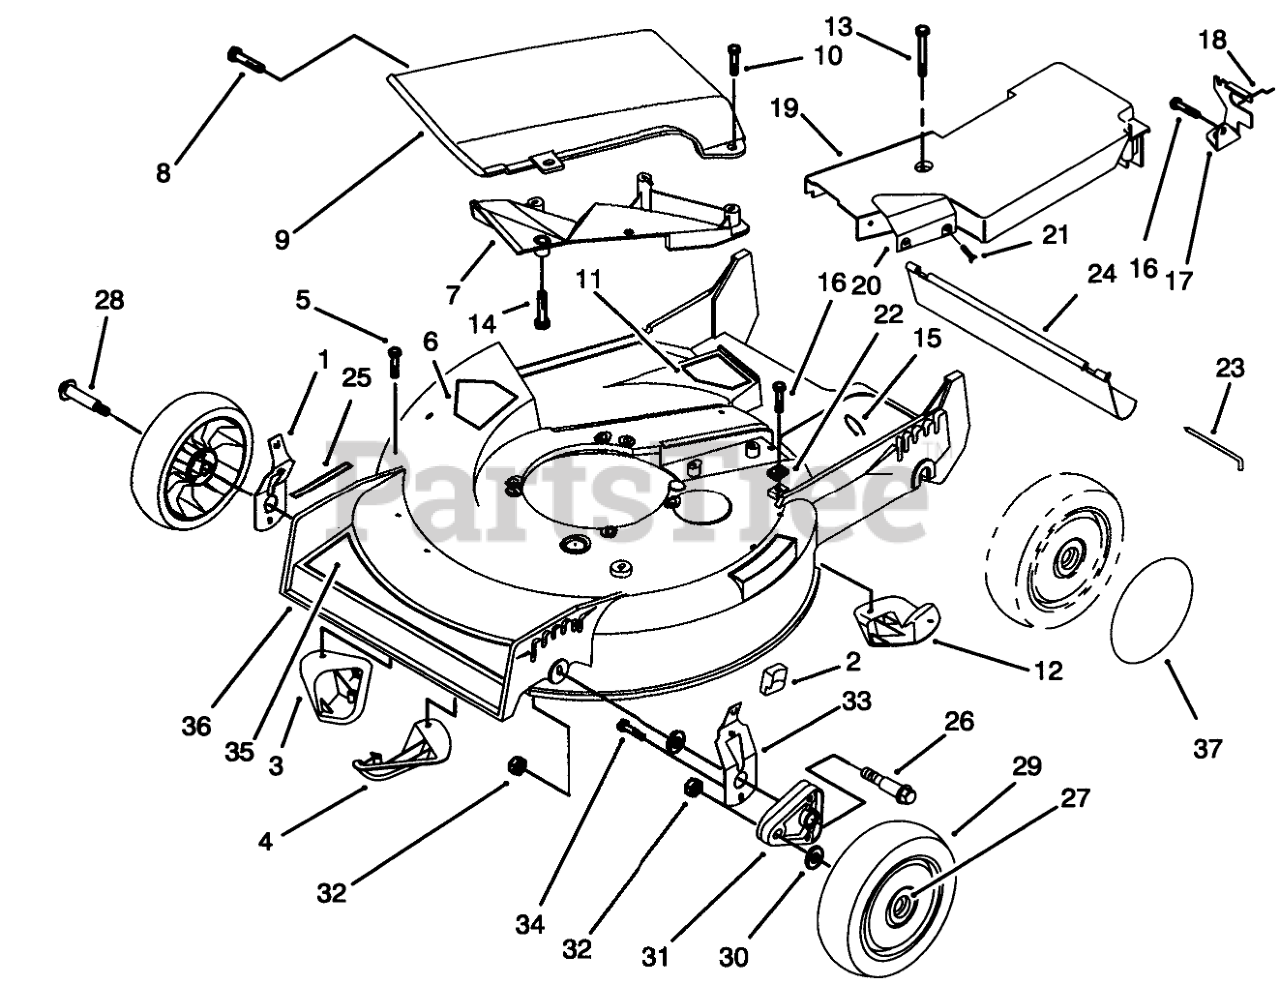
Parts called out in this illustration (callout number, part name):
1	RH SPRING ARM ASM
2	KNOB-ARM
3	KICKER-FRONT
4	KICKER-RH
5	SCREW-PPH
6	DECAL-DANGER
7	Deflector-Recycler
8	SCREW AND WASHER ASM
9	Cover Assembly (Incl. Ref. #7 & 14)
10	SCREW-HWH
11	DECAL - DANGER
12	KICKER-REAR
13	SCREW-HHFTF
15	TIE-CABLE
16	SCREW-HWHTF
17	Bracket-Adj. Trac
18	RETAINER-CABLE
19	Belt Cover Assembly (Incl. Ref. #20 & 21)
20	HEAT SHIELD
21	RIVET-HEAD, FLAT
22	CLAMP-CABLE
23	ROD-SHIELD
24	SHIELD-TRAILING
25	DECAL - HOC
26	BOLT-SHOULDER
27	BUSHING
28	BOLT-WHEEL
29	Wheel & Tire Assembly (Incl. Ref. #27)
30	WASHER
31	ARM-PIVOT, FRONT
32	NUT-LOCK
33	LH SPRING ARM ASM
34	SCREW-HWH
35	DECAL - DECK
36	Housing Assembly (Incl. Ref. #3-6, 8, 12, 16, & 25, pg.1-2) (Incl. Ref. #6, & 7 pg. 3)
37	WHEEL COVER
